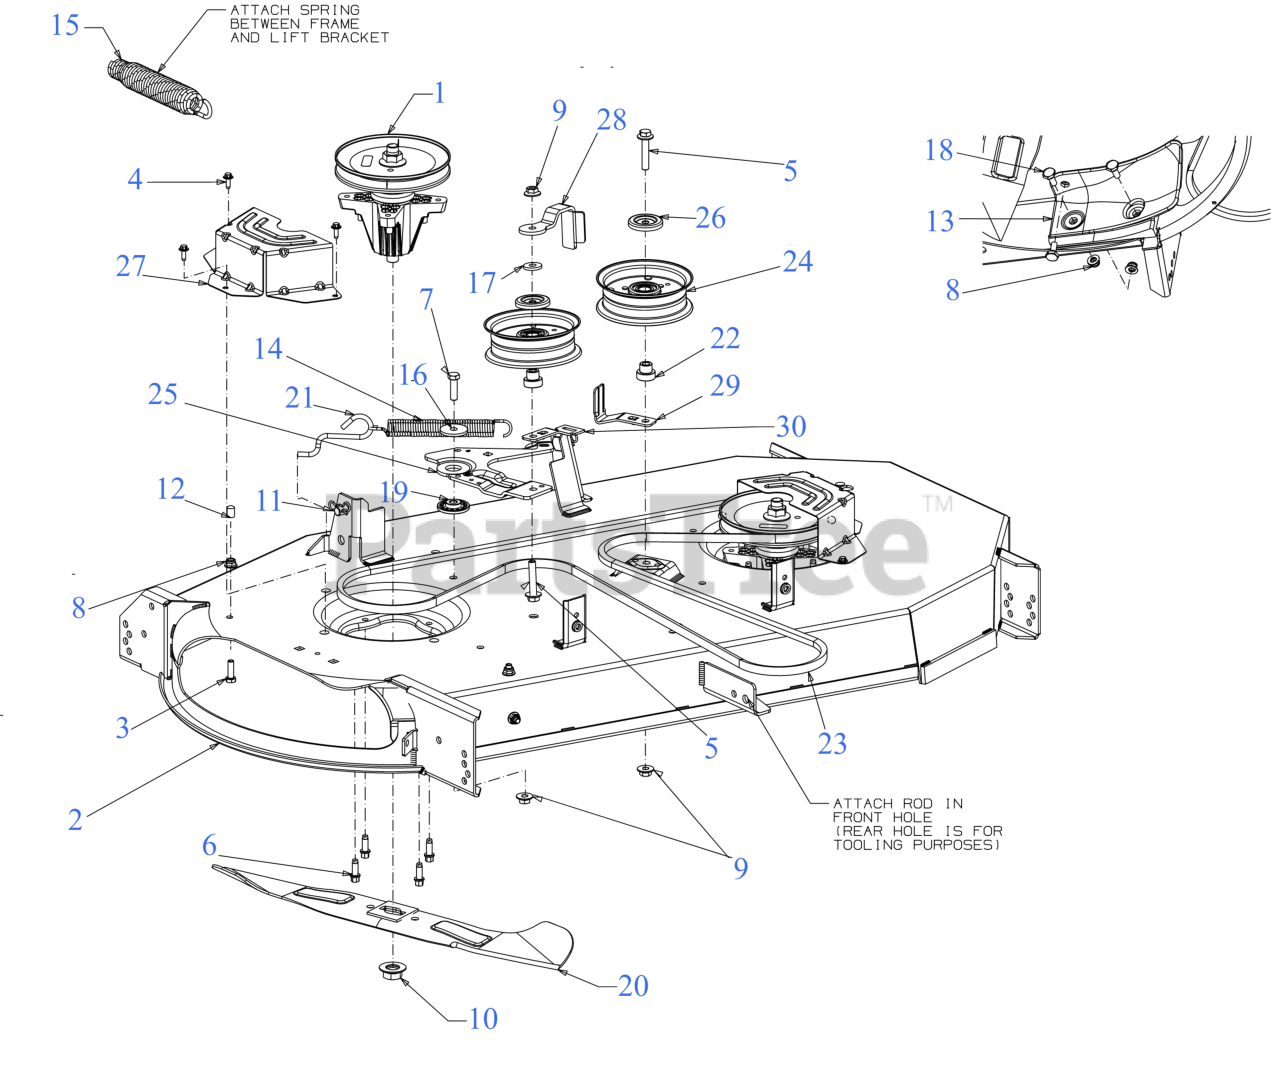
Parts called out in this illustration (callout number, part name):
1	SPINDLE ASSEMBLY (6.93 DIA)
3	SCREW 5/16-18 x 1.0 GR5
4	SCREW M6-1 x .625
5	SCREW 3/8-16 x 2.0
6	SCREW 5/16-18 x .875
7	SCREW 3/8-16 x 1.25 GR5
8	FLANGE LOCK NUT 5/16-18
9	FLANGE LOCK NUT
10	HEX FLANGE NUT 5/8-18 GR5
11	BOW TIE COTTER PIN
13	DISCHARGE BAFFLE
14	EXTENSION SPRING
15	LIFT ASSIST SPRING (LARGE)
16	FLAT WASHER .390x1.500x.134
17	FLAT WASHER .385 x 1.00 x .135
18	SHOULDER SCREW
19	SHOULDER SPACER
20	23.25" BLADE (2IN1) (S SHAPE CENTER HOLE)
20	Cub Cadet 46" HI LIFT BLADE SET (S SHAPE CENTER HOLE) (-05510)
20	23.25" XTREME BLADE (2IN1) (S SHAPE CENTER HOLE)
20	Cub Cadet 46" XTREME BLADE SET (S SHAPE CENTER HOLE) ( -05510-X)
20	23.25" LOW LIFT BLADE (S SHAPE CENTER HOLE)
20	Cub Cadet 46" LOW LIFT BLADE SET (S SHAPE CENTER HOLE) (-05510-L)
21	DECK SPRING HOOK
22	SHOULDER SPACER
23	V-BELT A SECX108.3
23	Troy-Bilt 46" DECK BELT
24	IDLER PULLEY 4.50" DIA
28	BELT KEEPER
